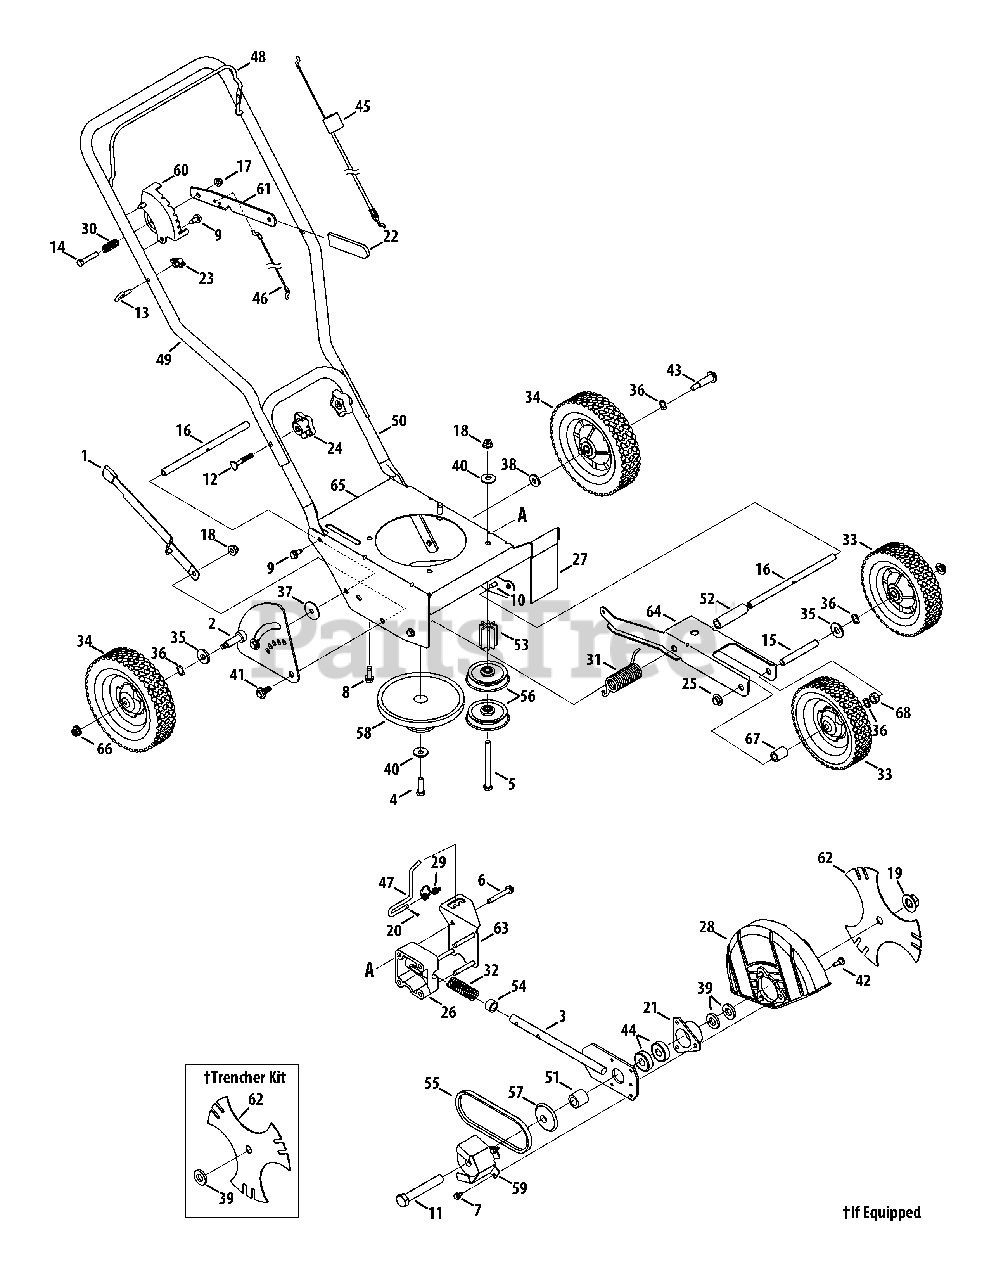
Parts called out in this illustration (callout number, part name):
1	Curb Height Adjustment Lever
2	Curb Height Adjuster Plate
3	Blade Plate Assembly
4	Screw 3/8-24
5	Screw 3/8-16
6	Hex Screw, 5/16-18
7	Self-tapping Screw, 1/4-20
8	Screw, 3/8-16
9	Hex Screw, 5/16-12
10	Hex Screw 5/16-18
11	Hex Screw, 5/8-18
12	Carriage Bolt, 5/16-18
13	Rope Guide (Eye Bolt)
14	Hex Screw, 5/16-18
15	Axle Shaft .50x6.65
16	Frame Spacer .50x9.25
17	Lock Flange Nut, 5/16-18
18	Flange Nut 3/8-16
19	Flange Nut, 5/8-18
20	Clevis Pin 3/32 x .625
21	Bearing Cup
25	Push Cap 1/2" rod
26	Bearing Block
27	Debris Guard
28	Blade Guard
29	Double Torsion Spring
30	Compression Spring
31	Torsion Spring
32	Compression Spring
33	Wheel 7 x 1.75 T-Tread
34	Wheel 8 x 1.75 T-Tread
35	Flat Washer, .531 x 1.25 x .181
36	Wave Washer .531 x .781 x .013
37	Flat Washer, .385 x 1.5 x .075
38	Flat Washer .385 x 1.0 x .135 †
39	Flat Washer .635x1.24x.181
40	Bell Washer,.396 x 1.140
41	Shoulder Screw, 3/8-16
42	Shoulder Screw
43	Shoulder Screw, 3/8-16
44	Bearing, .625 ID x 1.57 OD
45	Control Cable (Briggs & Stratton)
46	Wheel Adjustment Cable
47	Blade Adjustment Rod
48	Bail Handle
51	Spacer, .63 x 1.12 x 1.06
53	Pulley Mount Spacer
54	Spacer, .64 x.88 x .50
56	Flat Idler Pulley, 2.5 OD
58	Combination Flywheel Pulley
61	Depth Index Lever
62	Tri-Star Blade
63	Bracket Plate
64	Dual Wheel Bracket
65	Frame
66	Flange Lock Nut, 3/8-16
67	Spacer., .525 x .775 x .93
68	Spacer., .505ID x .88OD x .440
